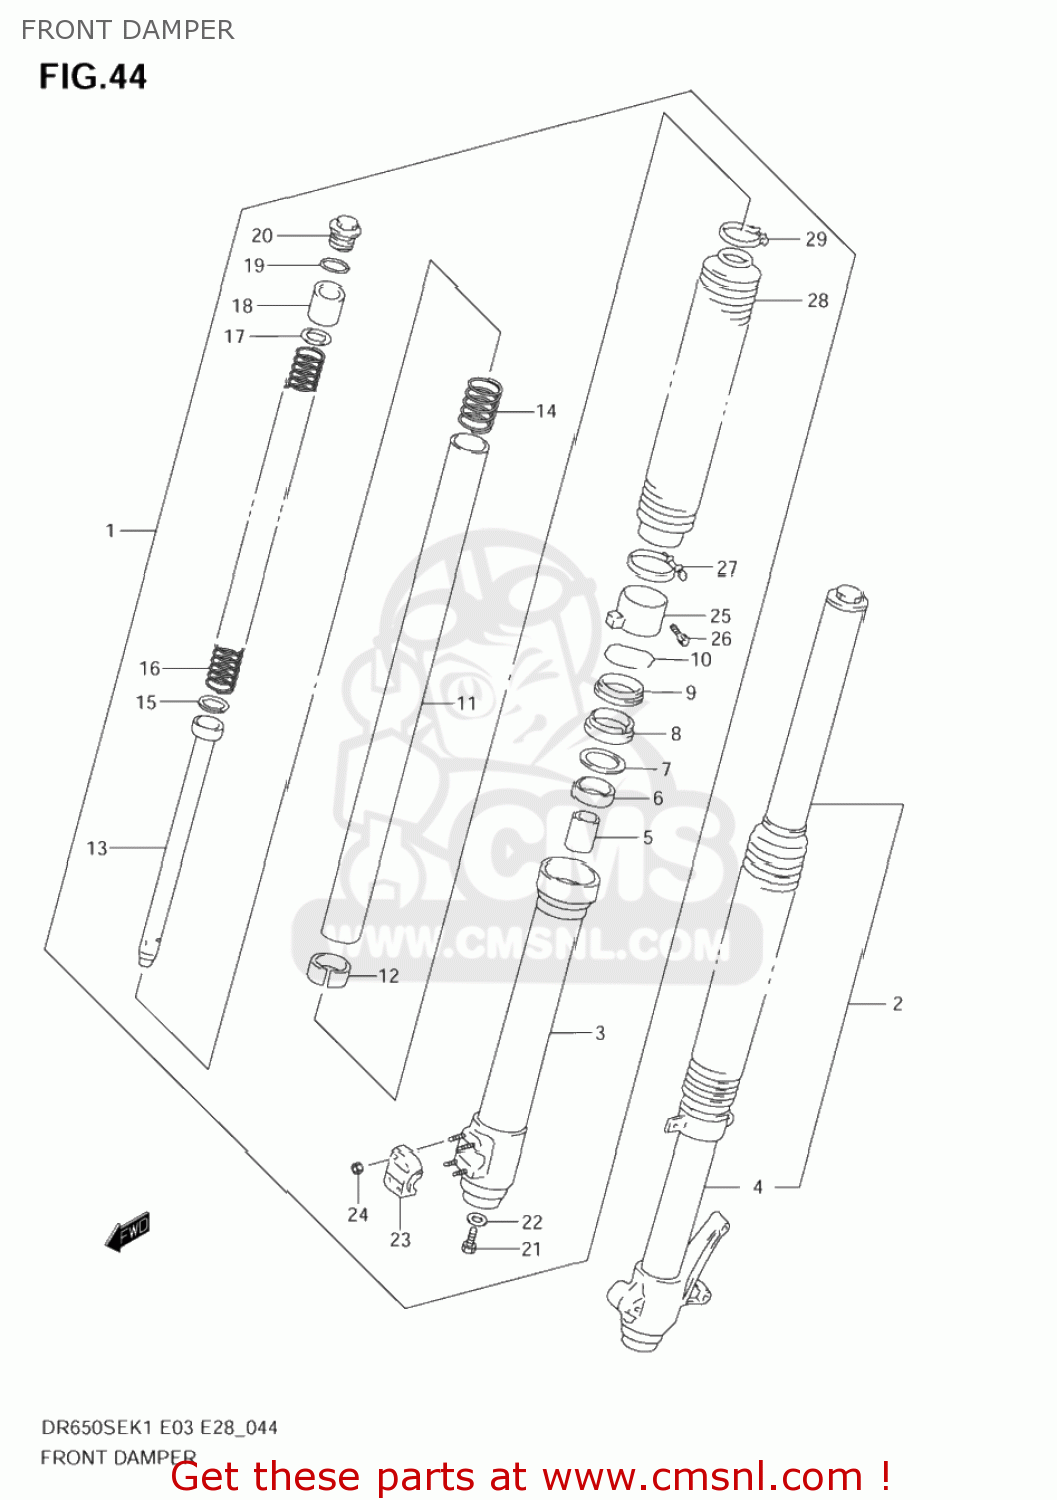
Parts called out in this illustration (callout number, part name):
1	DAMPER ASSY,FR FORK,R
2	DAMPER ASSY,FR FORK,L
3	TUBE,OUTER,R
4	TUBE,OUTER,L
5	PIECE,OIL LOCK
6	METAL,SLIDE
7	WASHER
8	SEAL,OIL
9	SEAL,DUST
10	RING,STOPPER
11	TUBE,INNER
12	PISTON
13	CYLINDER
14	SPRING,REBOUND
15	RING,PISTON
16	SPRING
17	WASHER
18	SPACER
19	O RING
20	CAP,FORK
21	BOLT,FORK CYLINDER(10X25)
22	GASKET (NAS)
23	HOLDER,AXLE,R
24	NUT
25	GUIDE,BOOT
26	BOLT
27	BAND,BOOT LWR
28	BOOT, BLACK
29	BAND,BOOT
